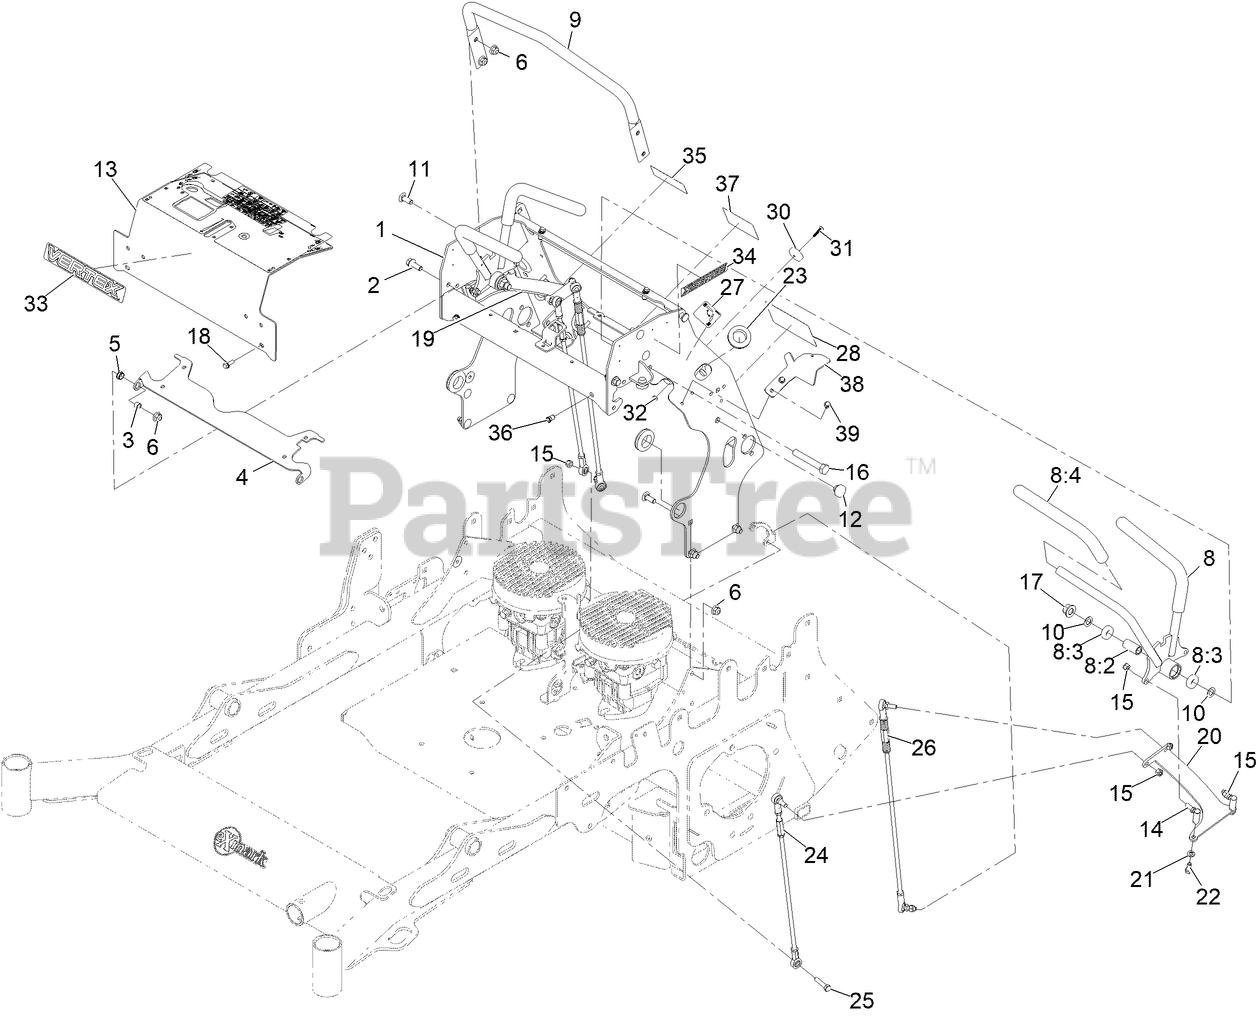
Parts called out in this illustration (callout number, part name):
1	ASM-TOWER
2	SCREW-HHF 3/8-16 X 1
3	SPACER-BRAKE PIVOT
4	PLATE-MOTION CNTRL LOCK
5	BUSHING,SNAP
6	NUT-HF, NI
8	ASM-CTRL LEVER
8:3	BEARING-WHEEL
8:4	GRIP-HANDLE, CONTROL
9	BAR-REFERENCE
11	SCREW-CARR
12	BUMPER-RUBBER
13	ASM-CONTROL PANEL W/DECAL
14	BALLJOINT-RH (W/GROMMET)
15	NUT-LOCK
16	SCREW-HH
17	Nut-Lock 1/2-13
18	SCREW-HHF
19	BRACKET-LINK CTRL LH
20	BRACKET-LINK CTRL RH
21	WASHER-LOCK
22	SCREW-HH
23	GROMMET
24	ASM-MOTION CONTROL SHORT
25	SCREW-HH
26	ASM-MOTION CONTROL LONG
27	DECAL-PARK BRAKE, CE
28	DECAL-SERVICE AID
30	MAGNET-RARE EARTH THIGH PAD
31	SCREW FLAT HD #10-24X1.00
32	NUT-LOCK
33	DECAL-VERTEX LOGO
34	DECAL-X-SERIES
35	DECAL-FUSE
36	Nut-Clinch, Hex
37	DECAL-DRIVE RELEASE
38	BRACKET-FUEL LINE CLAMP LH
39	SCREW-HWH
